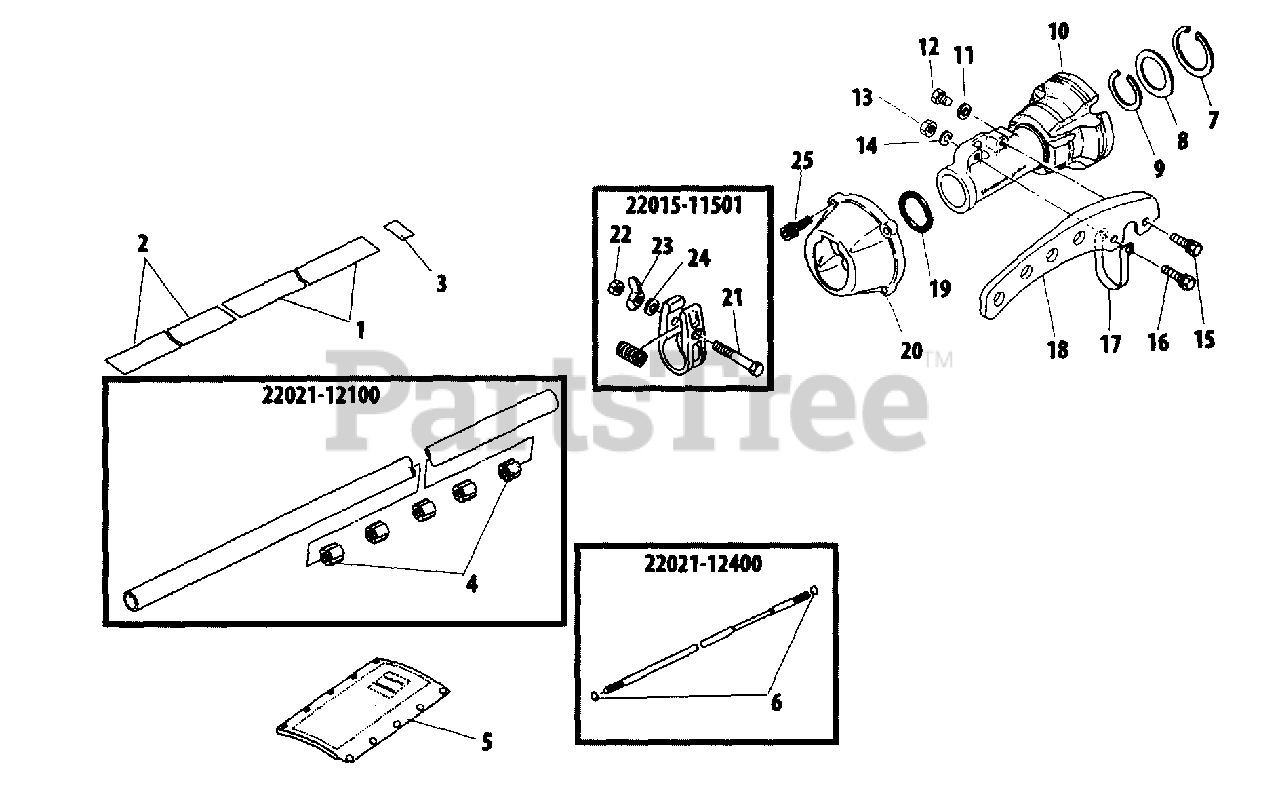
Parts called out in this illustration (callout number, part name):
1	LABEL - MODEL
2	LABEL - CAUTION
3	LABEL - ALIGNMENT
4	BUSHING
5	PROTECTOR
6	STOPPER
7	RING, RETAINING - 40
8	STOPPER
9	RING, RETAINING
10	SWIVEL JOINT
11	WASHER
12	BOLT - 6X8
13	NUT - 6
14	LOCKWASHER - 6
15	SCREW - 6X16
16	SCREW - 6X30
17	CLAMP
18	HANGER
19	O-RING
20	CONNECTOR, CAP
21	BOLT
22	LOCKNUT - 6
23	WINGNUT
24	WASHER - 6
25	SCREW - 5X20
22015-11501	SWIVEL LOCK ASSY
22021-12100	MAIN PIPE ASSY
22021-12400	SHAFT, MAIN
